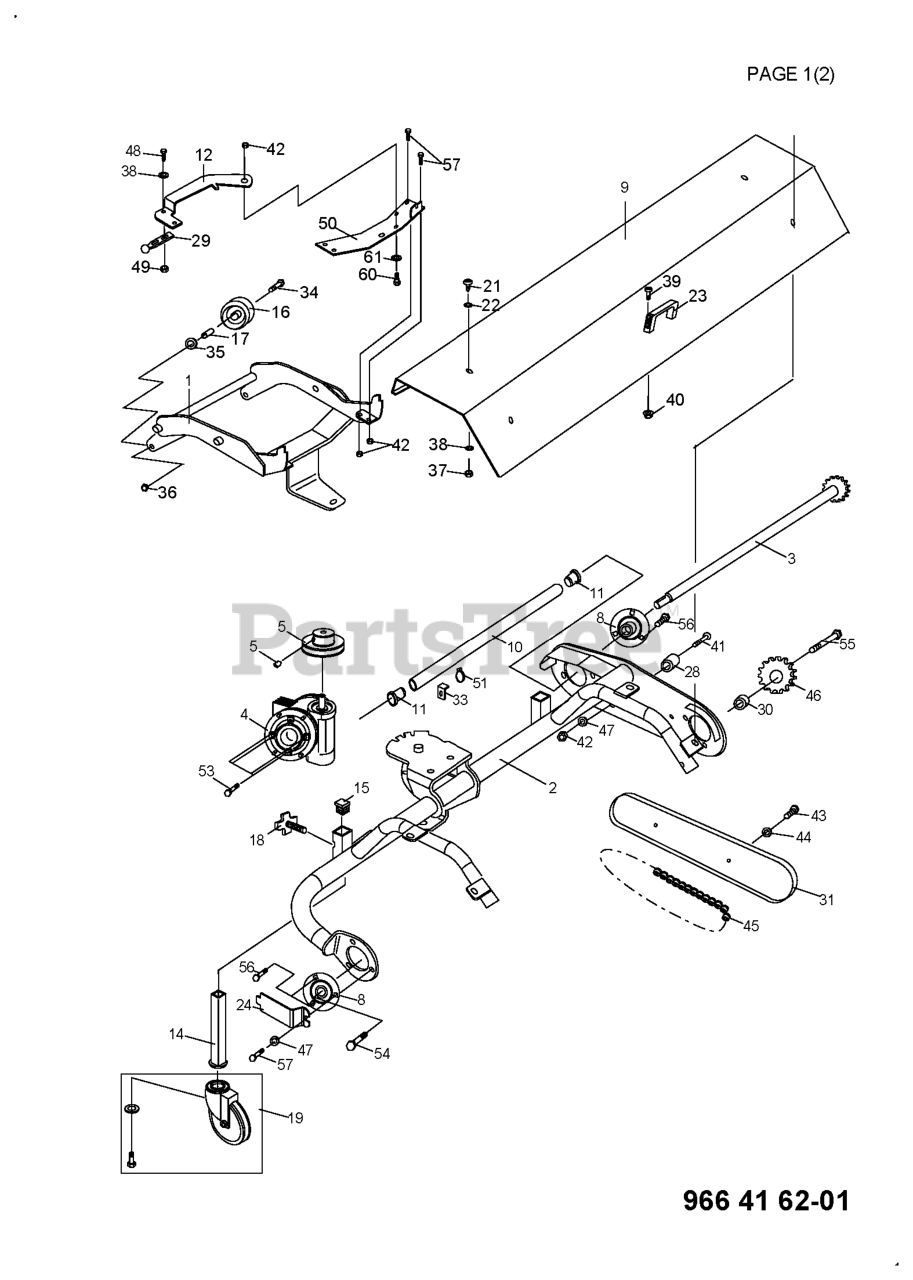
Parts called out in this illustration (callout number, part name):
1	FRAME BRACKET
2	FRAME BRACKET
3	DRIVE SHAFT
16	SUPPORT WHEEL
17	COLLAR
19	SUPPORT WHEEL
28	CHAIN ADJUSTER
29	Support Strap
40	NUT LOCKING
